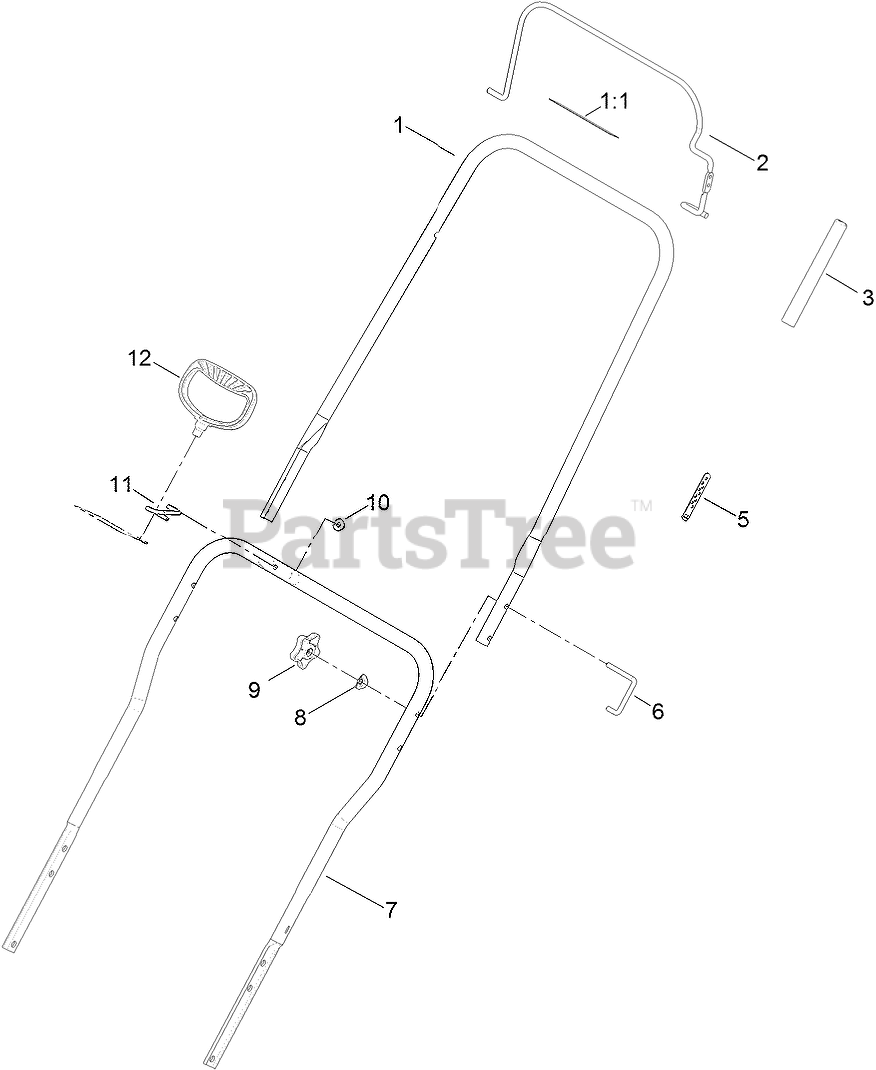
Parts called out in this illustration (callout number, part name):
1	UPPER HANDLE ASM
1:1	DECAL-DRIVE, ROTOR
2	BAIL-CLUTCH
3	COVER-SPRING
5	ADJUSTER-CABLE, CLUTCH
6	LOCK-HANDLE
7	HANDLE-LOWER
8	WASHER
9	KNOB-HANDLE
10	NUT-HEX FLG
11	GUIDE-ROPE
12	HANDLE-RECOIL
